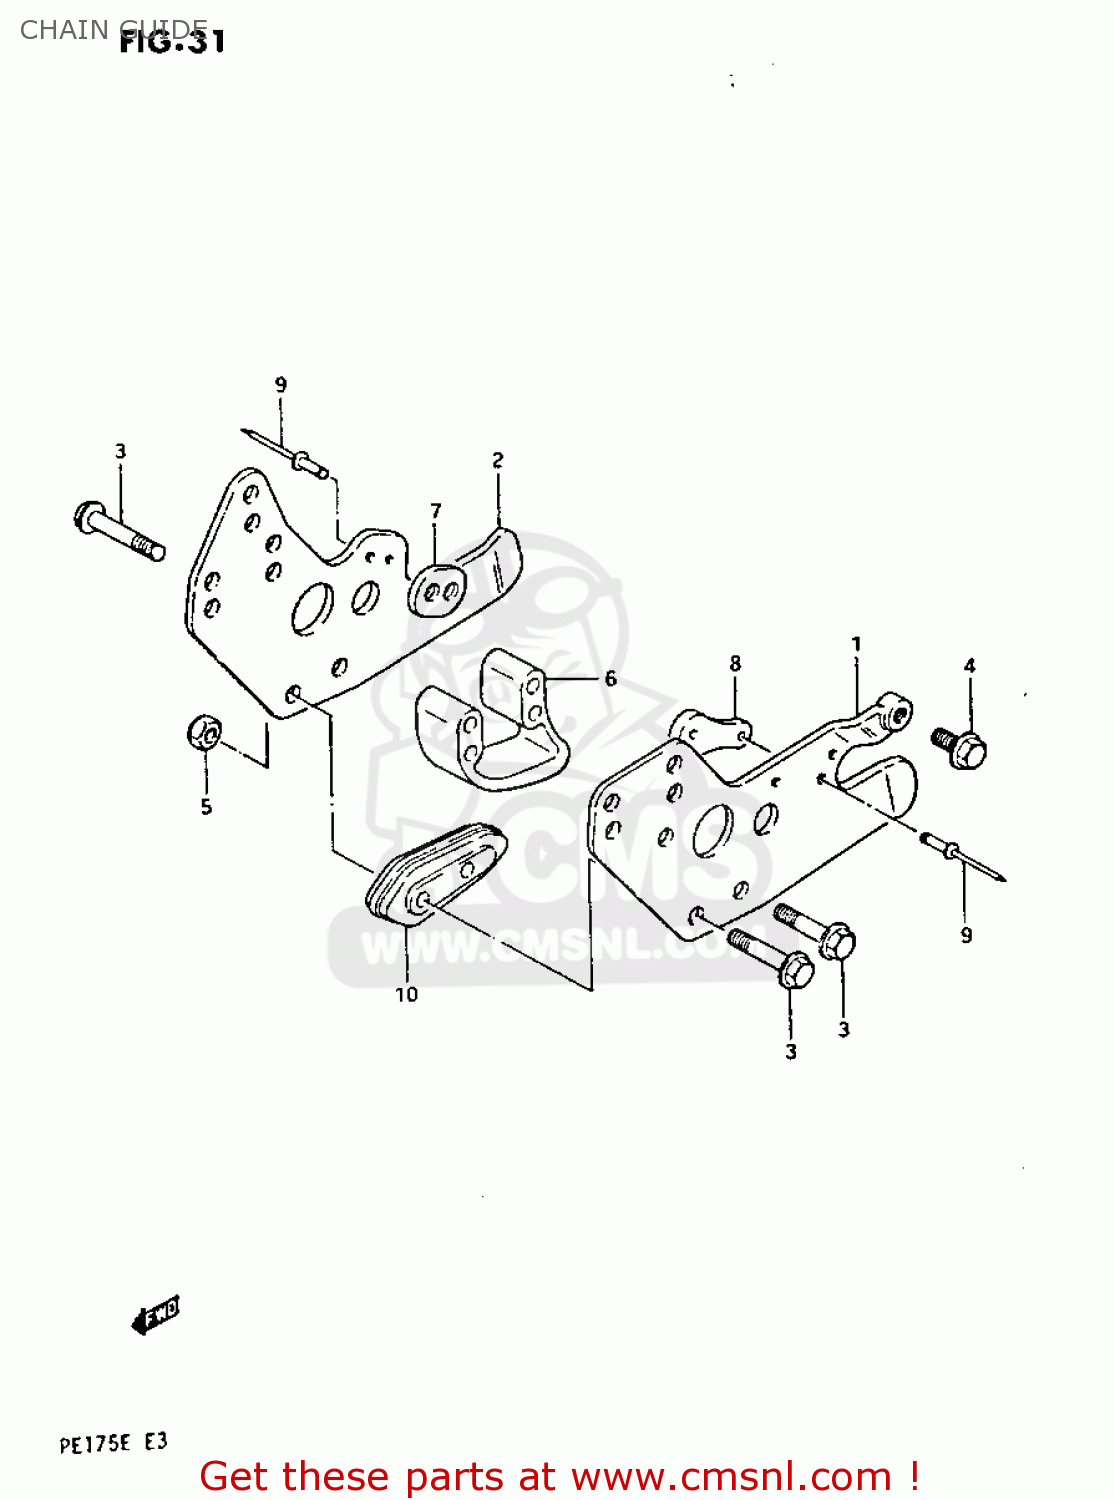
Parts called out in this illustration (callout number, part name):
1	PLATE,CHAIN GUIDE,OUTER
2	PLATE,CHAIN GUIDE,INNER
3	BOLT
4	BOLT
5	NUT
6	DEFENSE,CHAIN GUIDE,UPPER
7	PAD,CHAIN GUIDE
8	PAD,DRIVE CHAIN GUIDE
9	RIVET
10	DEFENSE,CHAIN GUIDE
